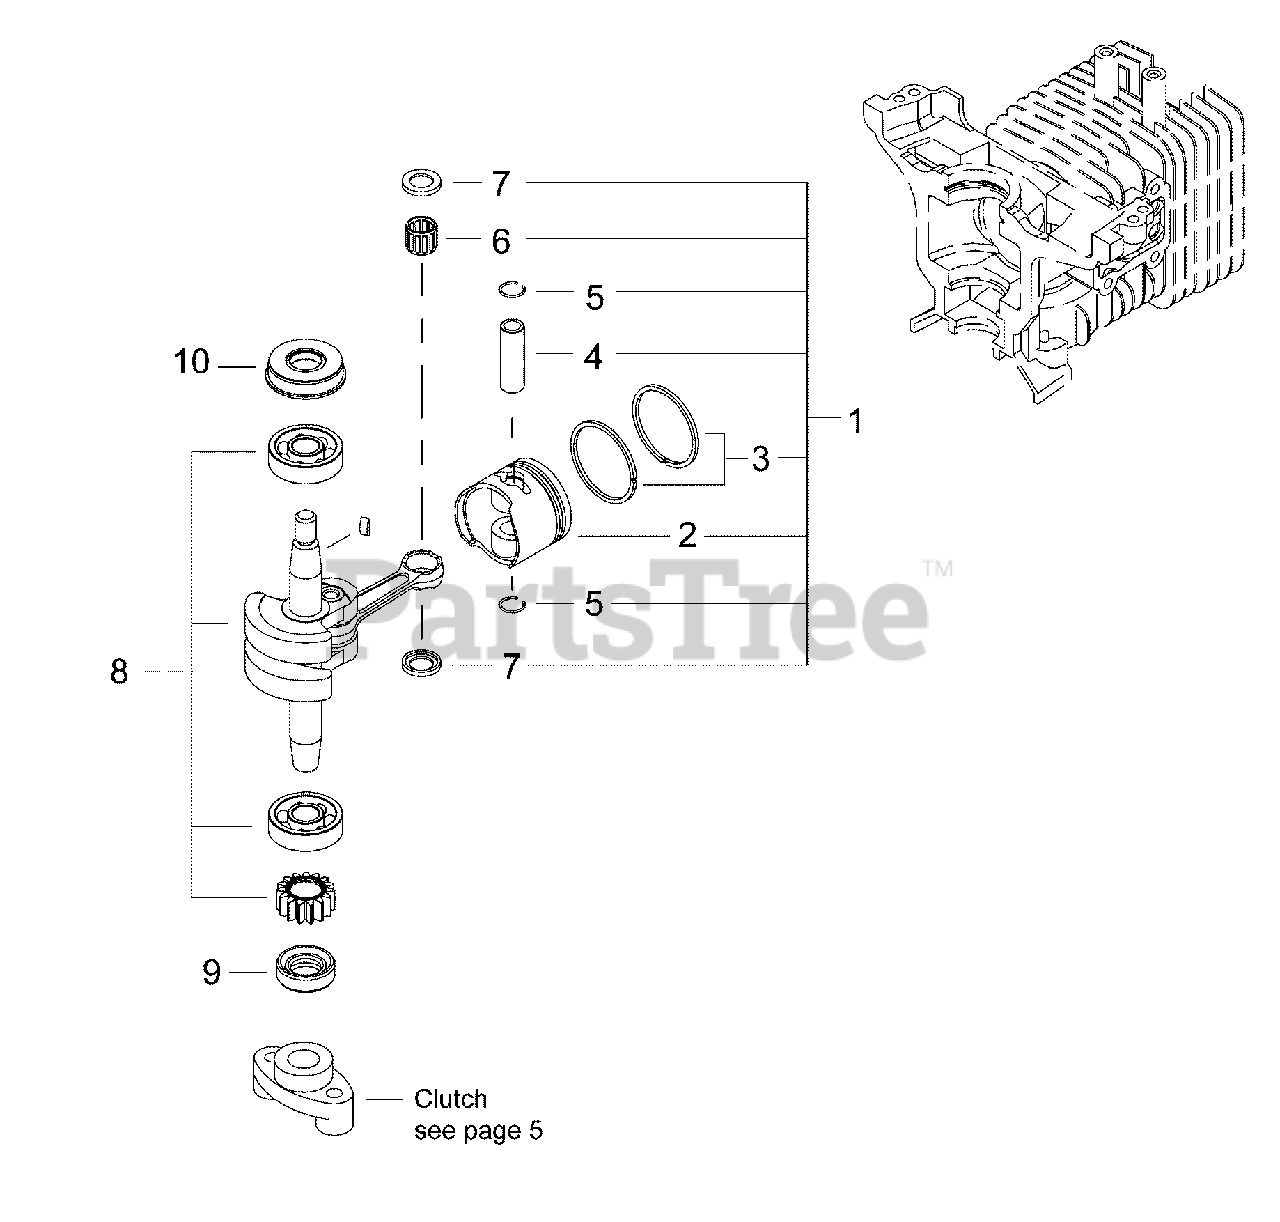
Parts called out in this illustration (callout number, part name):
1	PISTON KIT
2	PISTON
3	RING, PISTON
4	PIN, PISTON
5	RING, RETAINING
6	BEARING, NEEDLE
7	SPACER - 9
8	CRANKSHAFT ASSY
9	SEAL, OIL - 12
10	SEAL, OIL - 12
